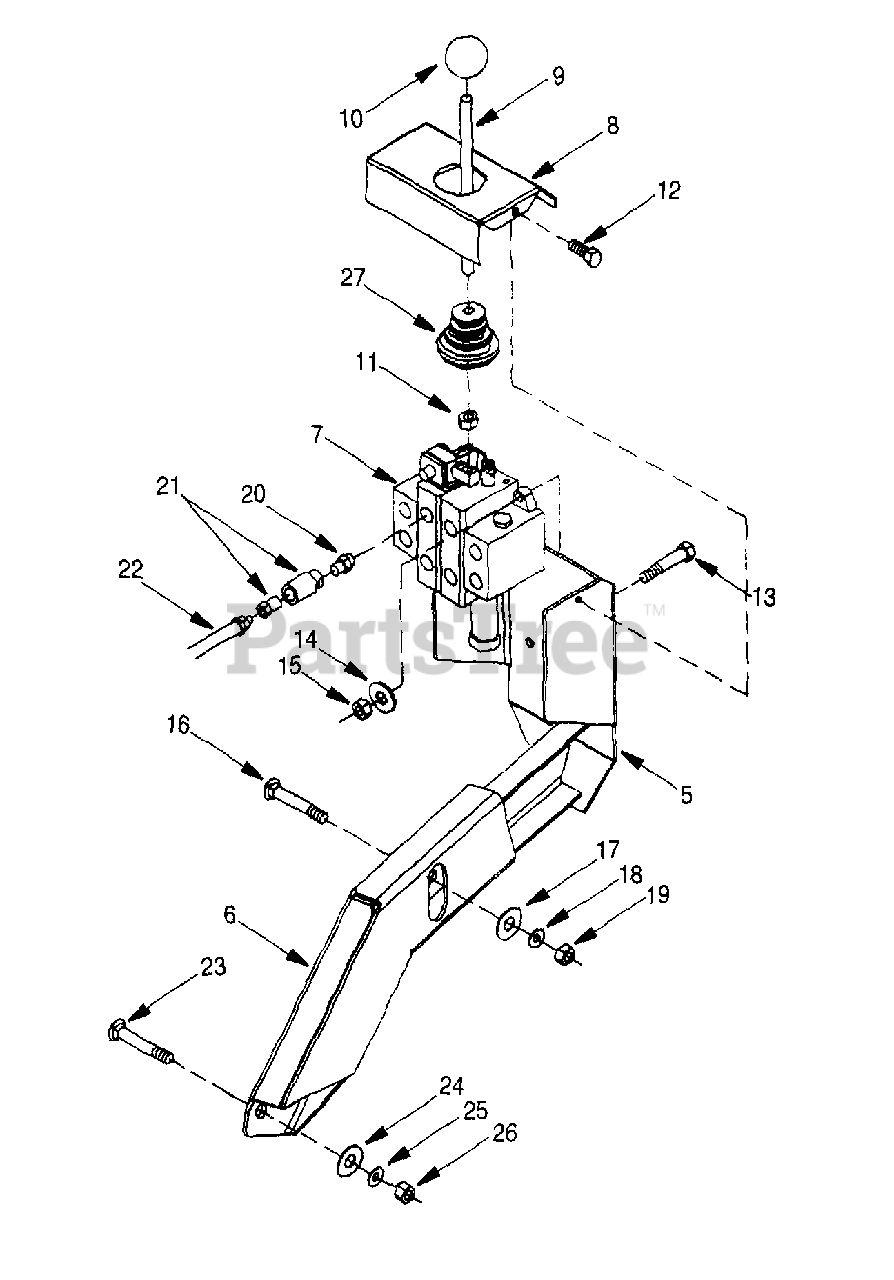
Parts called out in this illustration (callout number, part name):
5	Valve Bracket
6	Valve Adjustment Channel - Offset
7	Control Valve
11	1/2 NC Jam Nut
12	5/16 NC x .75 Self Tap Screw
13	3/8 NC x 1.25 Hex Hd Cap Screw GR5
14	3/8 Lockwasher
15	3/8 NC Nut
16	1/2 NC x 1.5 Carriage Bolt
17	112 Washer
18	1/2 Lockwasher
19	1/2 NC Nut
20	3/8 NPT Male Adapter Fitting
21	3/8 Hydraulic Coupler Set
22	Loader Feed Hose
23	5/8 NC x 1.5 Carriage Bolt
24	5/8 Washer
25	5/8 Lockwasher
26	5/8 NC Nut
27	Rubber Control Boot
